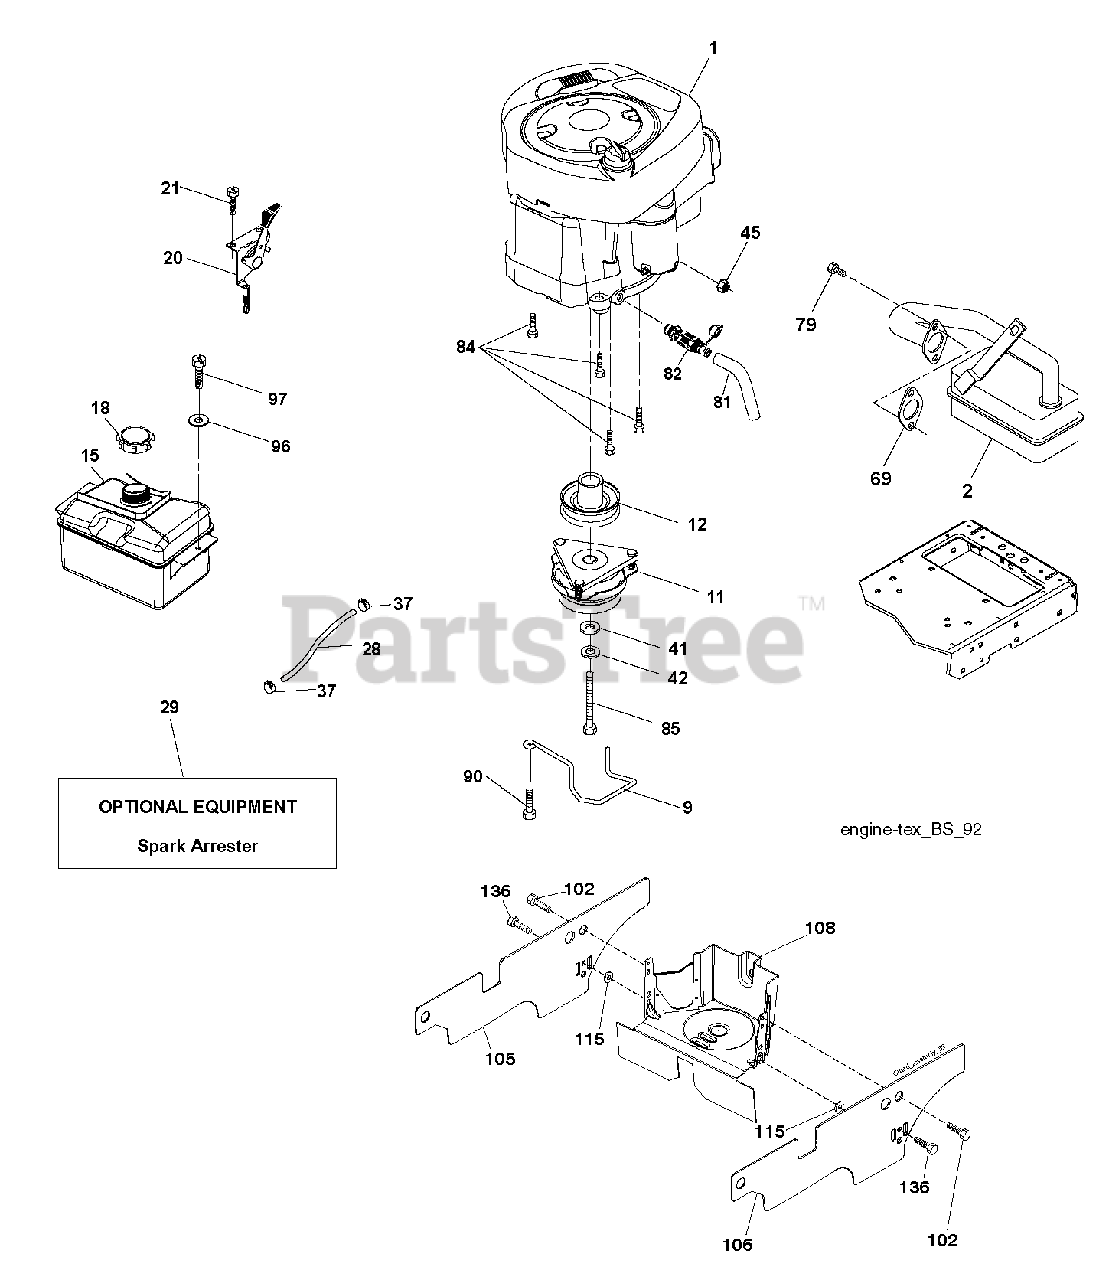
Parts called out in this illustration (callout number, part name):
2	MUFFLER.LT.BRIGGS.14HP.IC/OHV
9	KEEPER BELT ENGINE
11	RB.CLUTCH.OGURA.4.4.PD
12	PULLEY.ENGINE.TUFFTORQ
15	RP TANK FUEL FRT 1.5 GAL
18	CAP ASM.FUEL.2.25"FR.
20	CONTROL.TH/CK.C.
21	SCREW.#10 X 0.750.BOS
28	LINE.FUEL.20
29	KIT.SPARK ARRESTOR 794945 B&S
37	HOSE CLAMP
42	LOCKWASHER
45	NUT
69	REPL BY 532 27 22-93
79	SCREW.SOCKET HD.5/16-1
81	TUBE, DRAIN OIL ASM.
82	VALUE.OIL.DRAIN
84	SCREW.3/8-16
85	BOLT HEX 7/16-20X4-1/4"
90	SCREW 3/8-16X1
97	SCREW HEXWSHR 1/4-20X3/4
102	SCREW
105	SHIELD.SIDE.LH.3842"TEX FRENCH
106	SHIELD.SIDE.RH.3842"TEX FRENCH
108	ENGINE COVER
115	PALNUT 1/4
136	SCREW.1/4-20X5/8
